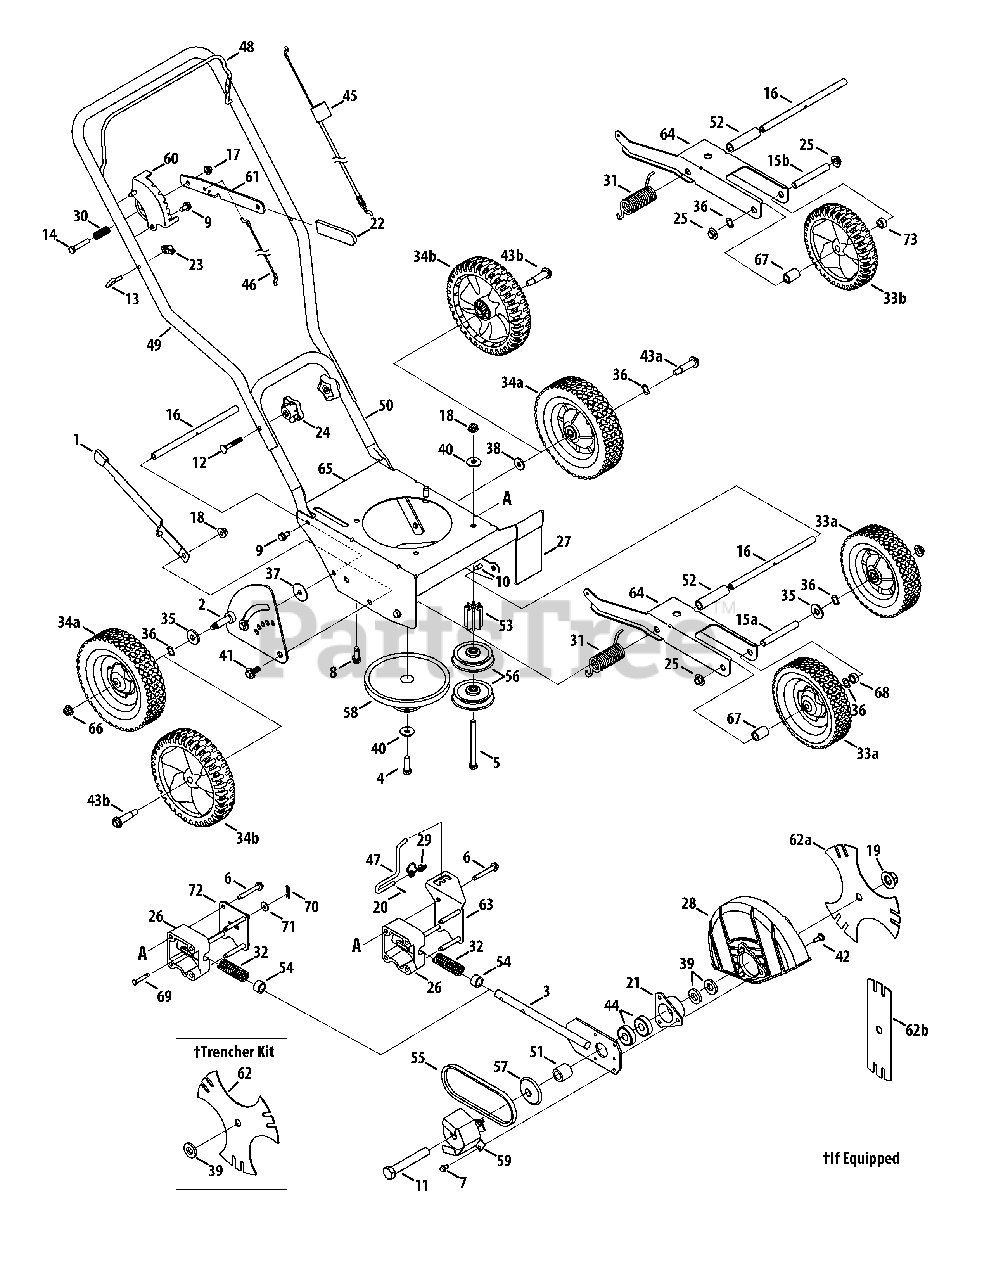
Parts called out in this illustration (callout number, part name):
1	Curb Height Adjustment Lever
2	Curb Height Adjuster Plate
3	Blade Plate Assembly
4	Screw 3/8-24
5	Screw 3/8-16
6	Hex Screw, 5/16-18
7	Self-tapping Screw, 1/4-20
8	Screw, 3/8-16
9	Hex Screw, 5/16-12
10	Hex Screw 5/16-18
11	Hex Screw, 5/8-18
12	Carriage Bolt, 5/16-18
13	Rope Guide (Eye Bolt)
14	Hex Screw, 5/16-18
16	Frame Spacer .50x9.25
17	Lock Flange Nut, 5/16-18
18	Flange Nut 3/8-16
19	Flange Nut, 5/8-18
20	Clevis Pin 3/32 x .625
21	Bearing Cup
23	Wing Nut
24	Star Knob
25	Push Cap 1/2" rod
26	Bearing Block
27	Debris Guard
28	Blade Guard
29	Double Torsion Spring
30	Compression Spring
31	Torsion Spring
32	Compression Spring
35	Flat Washer, .531 x 1.25 x .181
36	Wave Washer .531 x .781 x .013
37	Flat Washer, .385 x 1.5 x .075
38	Flat Washer .385 x 1.0 x .135
39	Flat Washer .635x1.24x.181
40	Bell Washer,.396 x 1.140
41	Shoulder Screw, 3/8-16
42	Shoulder Screw
44	Bearing, .625 ID x 1.57 OD
45	Control Cable (Briggs & Stratton)
46	Wheel Adjustment Cable
47	Blade Adjustment Rod
48	Bail Handle
51	Spacer, .63 x 1.12 x 1.06
52	Spacer
53	Pulley Mount Spacer
54	Spacer, .64 x.88 x .50
56	Flat Idler Pulley, 2.5 OD
57	Sheave
58	Combination Flywheel Pulley
59	Belt Guard
61	Depth Index Lever
62	Tri-Star Blade (pack of 6)
63	Bracket Plate
64	Dual Wheel Bracket
65	Frame
66	Flange Lock Nut, 3/8-16
67	Spacer., .525 x .775 x .93
68	Spacer., .505ID x .88OD x .440
69	Clevis Pin, .250 x 1.53
70	Cotter Pin, .072 x 1.12
71	Flat Washer, .283 x .75 x .030
72	Cover Plate
73	Spacer, .525 x .775 x .3125
